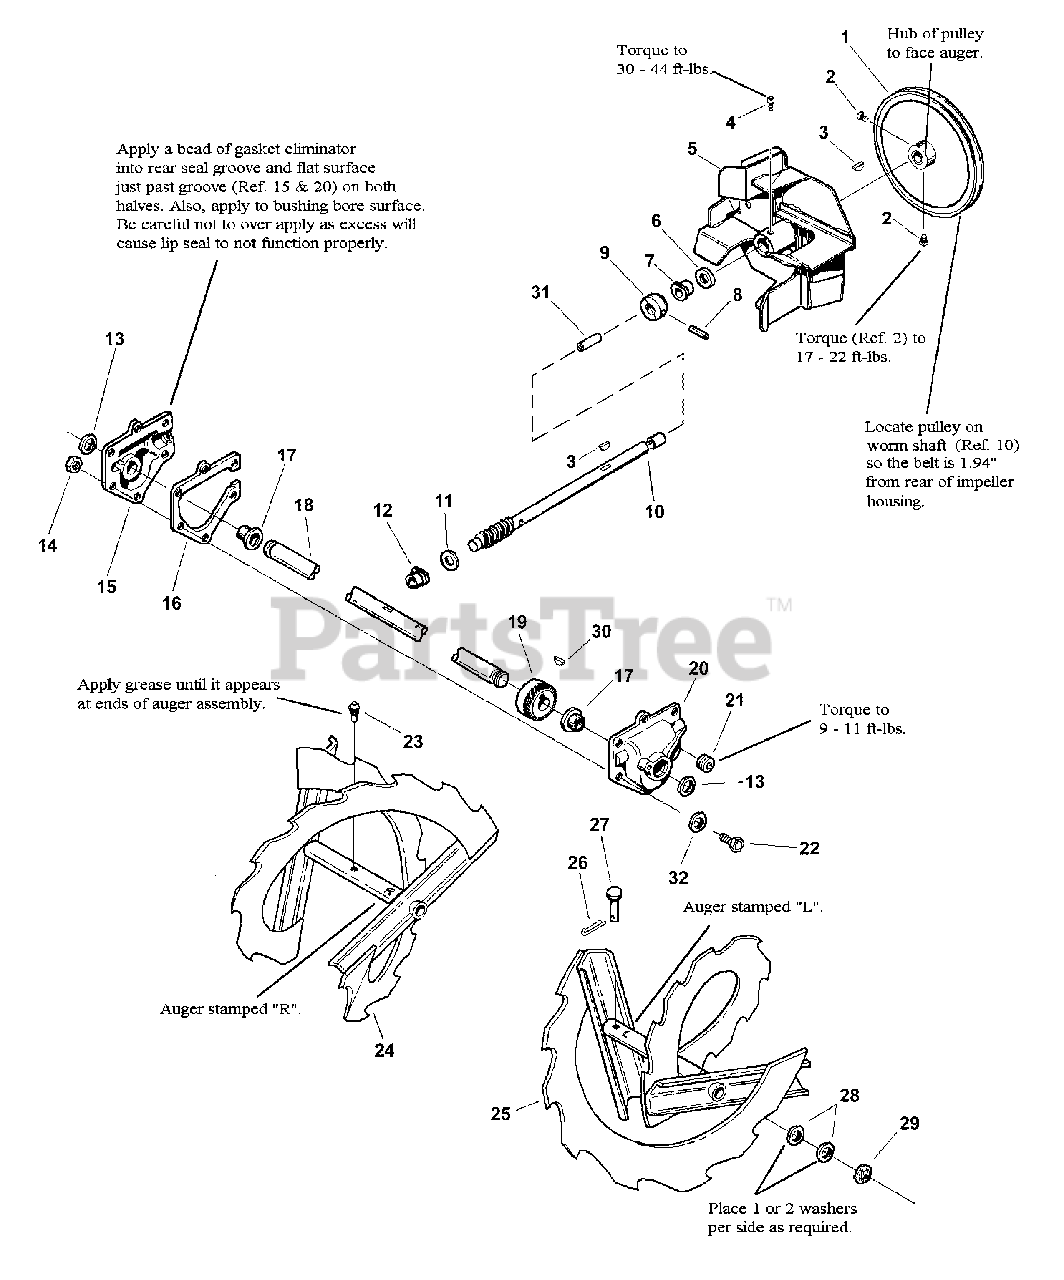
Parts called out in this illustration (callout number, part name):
1	PULLEY, Auger Input
2	SET SCREW, 5/16-18 x 1/2" Square Head Cup Point
3	KEY, 3/16 x 3/4" Woodruff
4	SET SCREW, 3/8-16 x 1/2" Square Head
5	IMPELLER ASSEMBLY
8	PIN, Drive-Loc, 3/16 x 1-1/2"
9	COLLAR, Thrust
10	SHAFT, Rolled Worm
11	WASHER, Thrust (.562 ID x 1.000 OD x .030/.032 Thick)
12	FLANGE, Bushing
14	NUT 1/4-20 Hex Center Lock
15	GEAR CASE, RH- Intermediate
16	GASKET, Gear Case
18	SHAFT, Auger, 22"/24"
20	GEAR CASE, LH- Intermediate
21	PIPE PLUG, 1/8-27 NPTF 3/4 Taper x .31 Long Hex Drive
22	SCREW, 1/4-20 x 7/8" Hex Head Cap, GR 5
23	FITTING, Grease
24	AUGER ASSEMBLY, 22" RH
25	AUGER ASSEMBLY, 22" LH
26	COTTER PIN, 3/32 x 3/4"
27	SHEAR PIN, .248 ID x 1-3/4" Long
28	WASHER
29	RING, Retaining
30	KEY, #605 Woodruff
31	TUBE, Low Density Polyethylene Extruded
32	FLAT WASHER, .268 ID x .591 OD x .063 Thick
